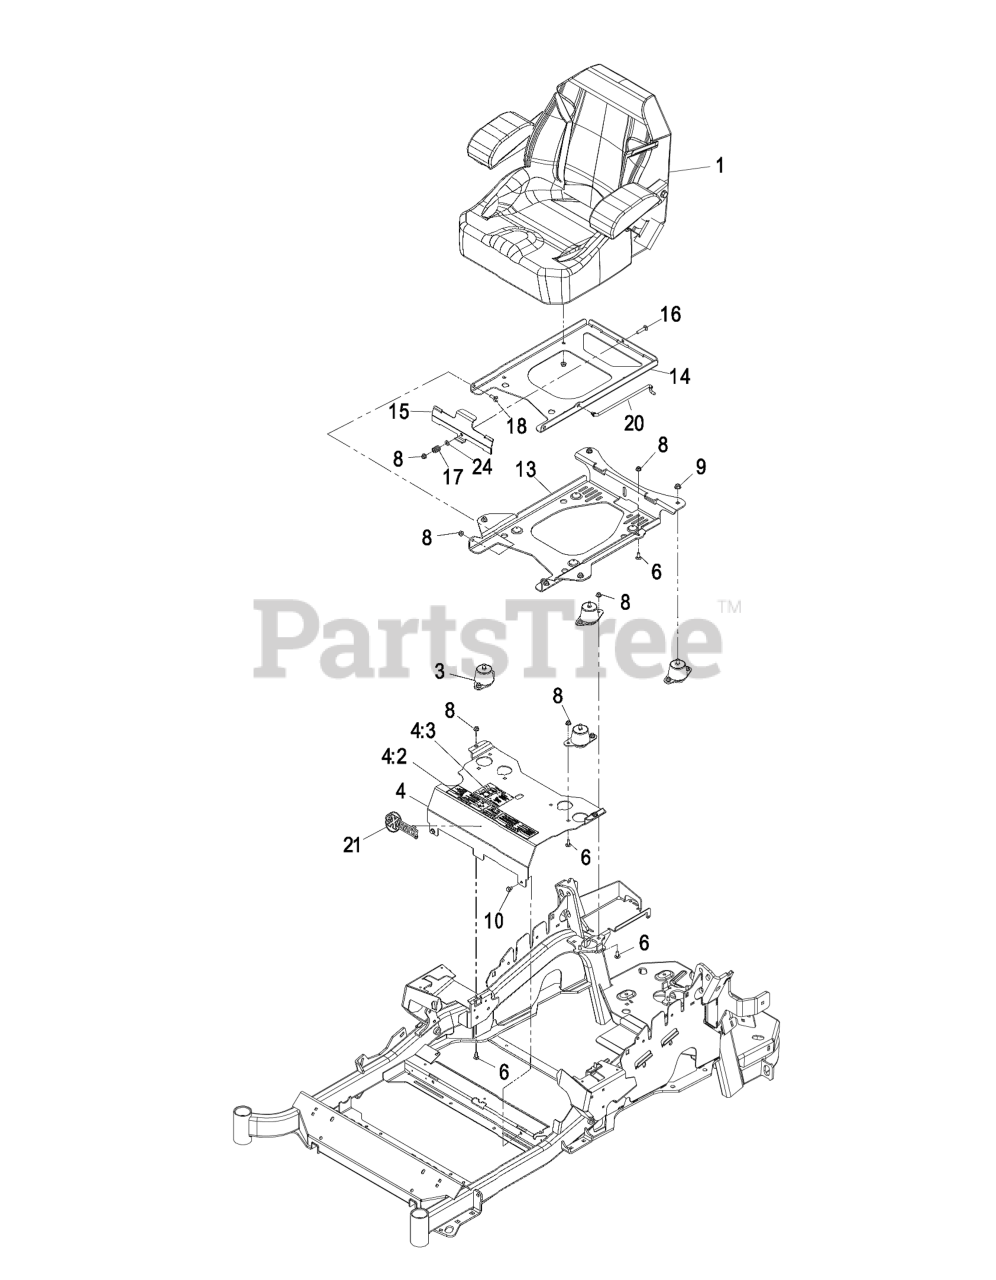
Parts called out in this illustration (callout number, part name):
3	ISOLATOR-SEAT
4:2	DECAL-CONSOLE
4:3	DECAL-SERVICE AID
6	SCREW-CARR
8	NUT-HF, NI
9	NUT-HF, NI
13	PLATE-SUPPORT, SEAT TILT
14	PLATE-FRAME, SEAT TILT
15	PLATE-LATCH, SEAT
16	BOLT-CARR
17	SPRING-COMPRESSION
18	SCREW-SHOULDER
20	ROD-PROP
24	WASHER-PLAIN
